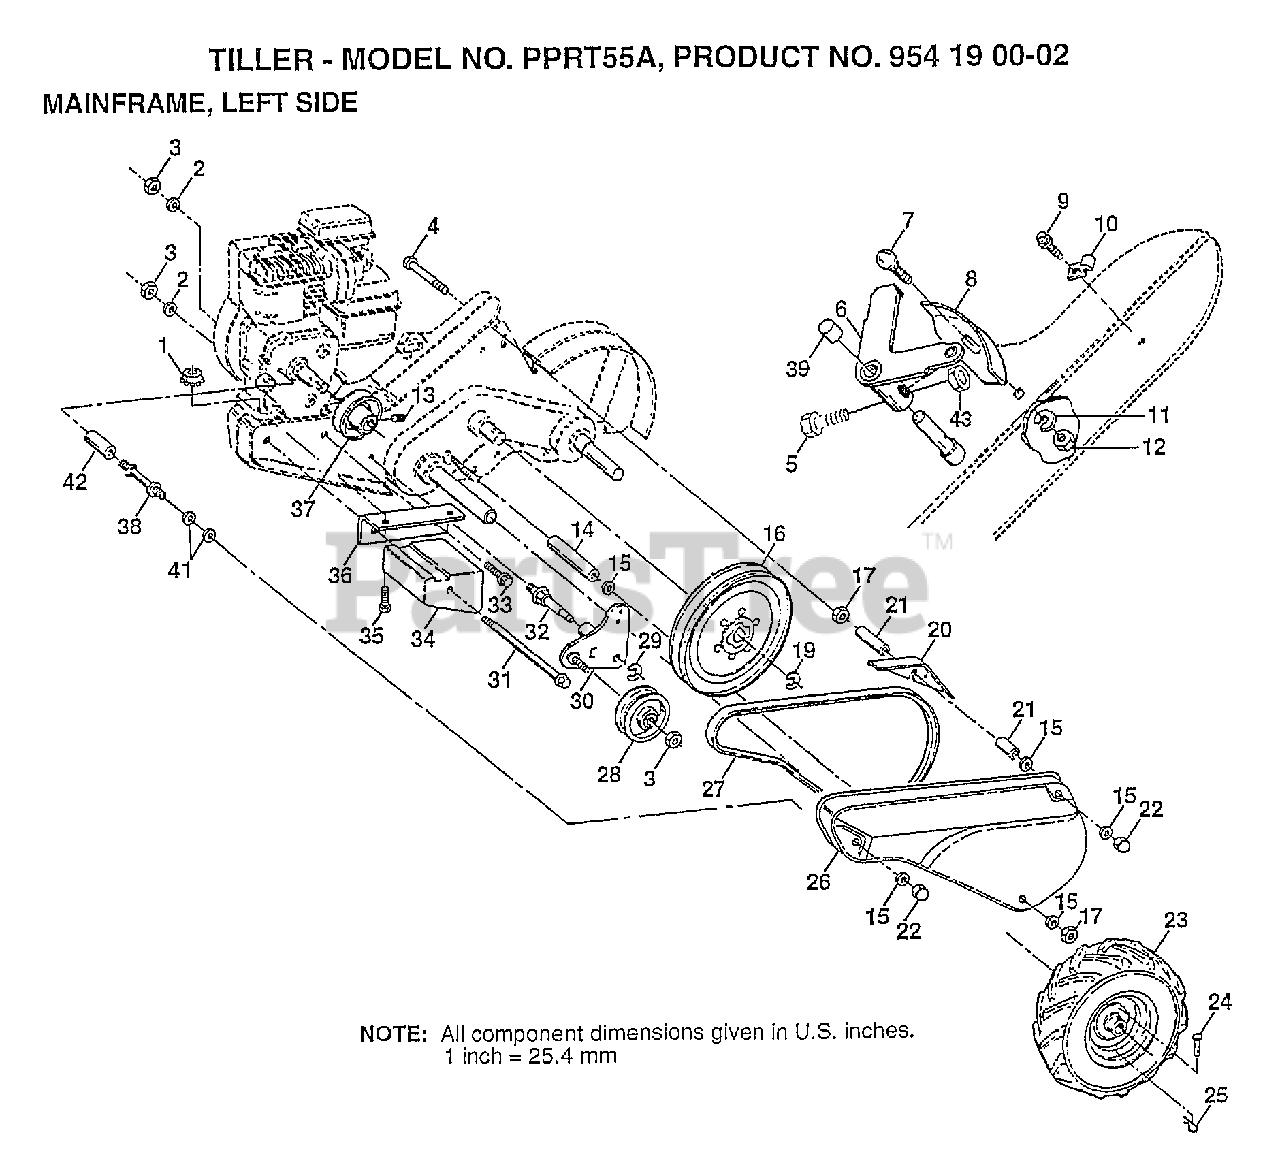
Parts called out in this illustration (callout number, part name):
2	LOCKWASHER
3	NUT.HEX.3/8-16UNC
4	BOLT TI
5	"SCREW-LEVER,SHI"
6	LEVER SHIFT
7	BOLT
8	PANEL TI
10	CONDIUT CLIP T
11	LOCKWASHER
13	SET SCREW
14	SPACER, SPLIT
15	WASHER
16	SHEAVE, TRANSMISSION
17	NUT.HEX.5/16-18
20	GUARD, PINCH POINT
21	SPACER SPLIT
23	TIRE TI
24	RIVET DRILLED
27	BELT-V
28	PULLEY, IDLER
29	KLIP RING
30	BRACKET, IDLER
32	SHAFT, IDLER ARM
33	BOLT
34	COUNTERWEIGHT
35	BOLT
36	BRACKET, REINFORCEMENT
37	ENGINE PULLEY
38	STUD.GUARD.BELT
39	CAP PLUNGER BLACK
41	WASHER
43	LOCKNUT
